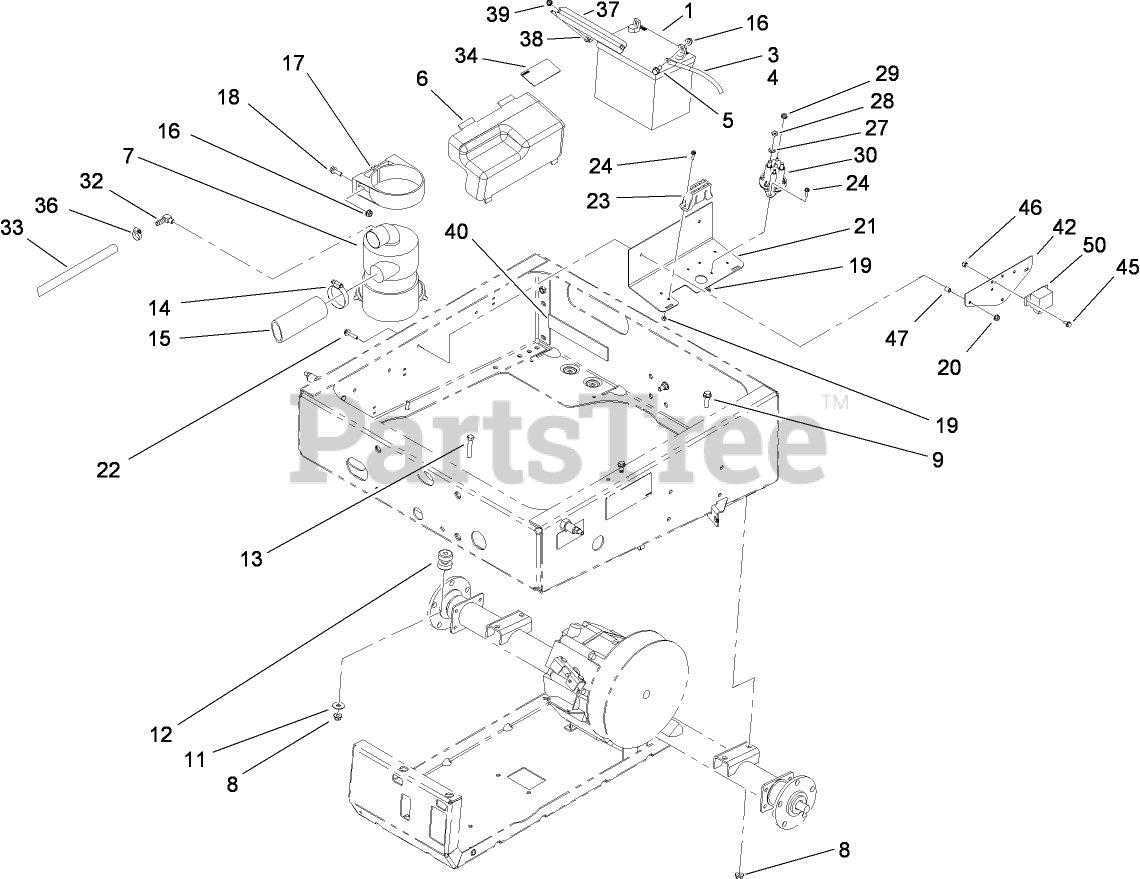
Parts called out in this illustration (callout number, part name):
1	BATTERY-DRY
4	CABLE-POSITIVE
5	SCREW-HHF
6	COVER-ELECTRICAL
7	AIR CLEANER ASM
8	NUT-HF, NI
9	SCREW-HHF
11	WASHER-FLAT
12	MOUNT-ISO
13	SCREW-HH
14	CLAMP-HOSE
15	HOSE-INTAKE
16	NUT-HF, NI
17	BRACKET-MOUNTING
18	SCREW-HHF
19	NUT-LOCK, NI
20	NUT-HHF
21	MOUNT-COMPONENT
22	SCREW-HHF
23	HARNESS-WIRE, MAIN
24	SCREW-HWH
27	WASHER-LOCK
28	NUT-JAM
29	NUT-KEPS
30	SOLENOID
32	FITTING-90 DEG
33	HOSE-BREATHER
34	DECAL-INFORMATION
36	CLAMP-HOSE
37	CLAMP-BATTERY
38	HOOK-RETAIN, BATTERY
39	NUT-HF
40	PAD-BATTERY
42	BRACKET-IGNITION
45	SCREW-HHF
46	NUT-LOCK, NI
47	SPACER
50	RELAY
